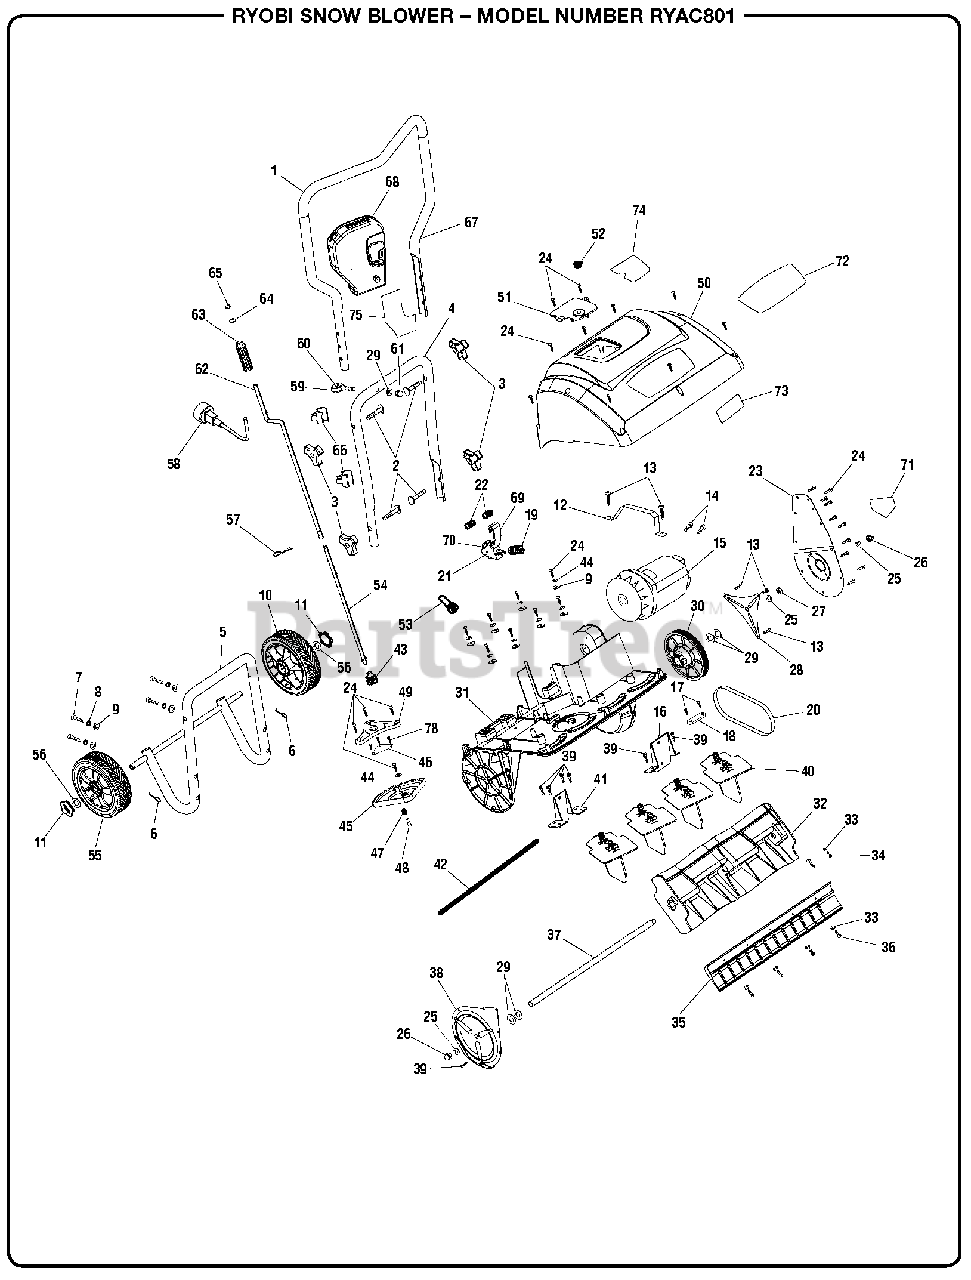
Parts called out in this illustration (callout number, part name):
2	Bolt (M8 x 50 mm))
4	Handle (Middle)
5	Handle (Lower)
7	Screw (M6 x 40 mm)
8	Spring Washer
9	Flat Washer (M6)
10	Wheel (Left)
12	Motor Bracket
13	Screw (M5 x 20 mm)
14	Screw (M5 x 18 mm))
15	Motor Assembly
16	Left Bracket
17	Screw (M4 x 20 mm)
18	Wire Clamp.
19	Spring (Tension Wheel)
21	Board (Tension Wheel)
22	Spring (Tension Wheel)
24	Screw (M4 x 15 mm)
25	Washer (M10)
28	Pulley Bracket
29	Washer (ID13.5 x 1.5 t)
30	Belt Pulley Assembly
31	Lower Housing
33	Washer (M4).
34	Screw (M4 x 13 mm)
36	Screw (M4 x 13 mm)
37	Auger Shaft
39	Screw (M4 x 13 mm)
40	Snow Direction Finj
41	Steel Bracket (Right)
42	Connection Rod.
44	Washer (M8)
46	Metal Plate
47	Gear Spring
48	Spring Board
50	Upper Housing
52	Rubber Seal Ring
53	Rubber Bushing
55	Wheel (Right)
56	Washer (ID13 x 2t)
60	Rubber Eyelet
64	Washer (M5)
67	Upper Handle
69	Bracket (Tension Wheel)
71	Danger Label (No Hands/Feet)
72	Performance/Logo Label
73	Chute Icon Label
74	Data/Warning Label
75	Starting Instructions/Logo Label
